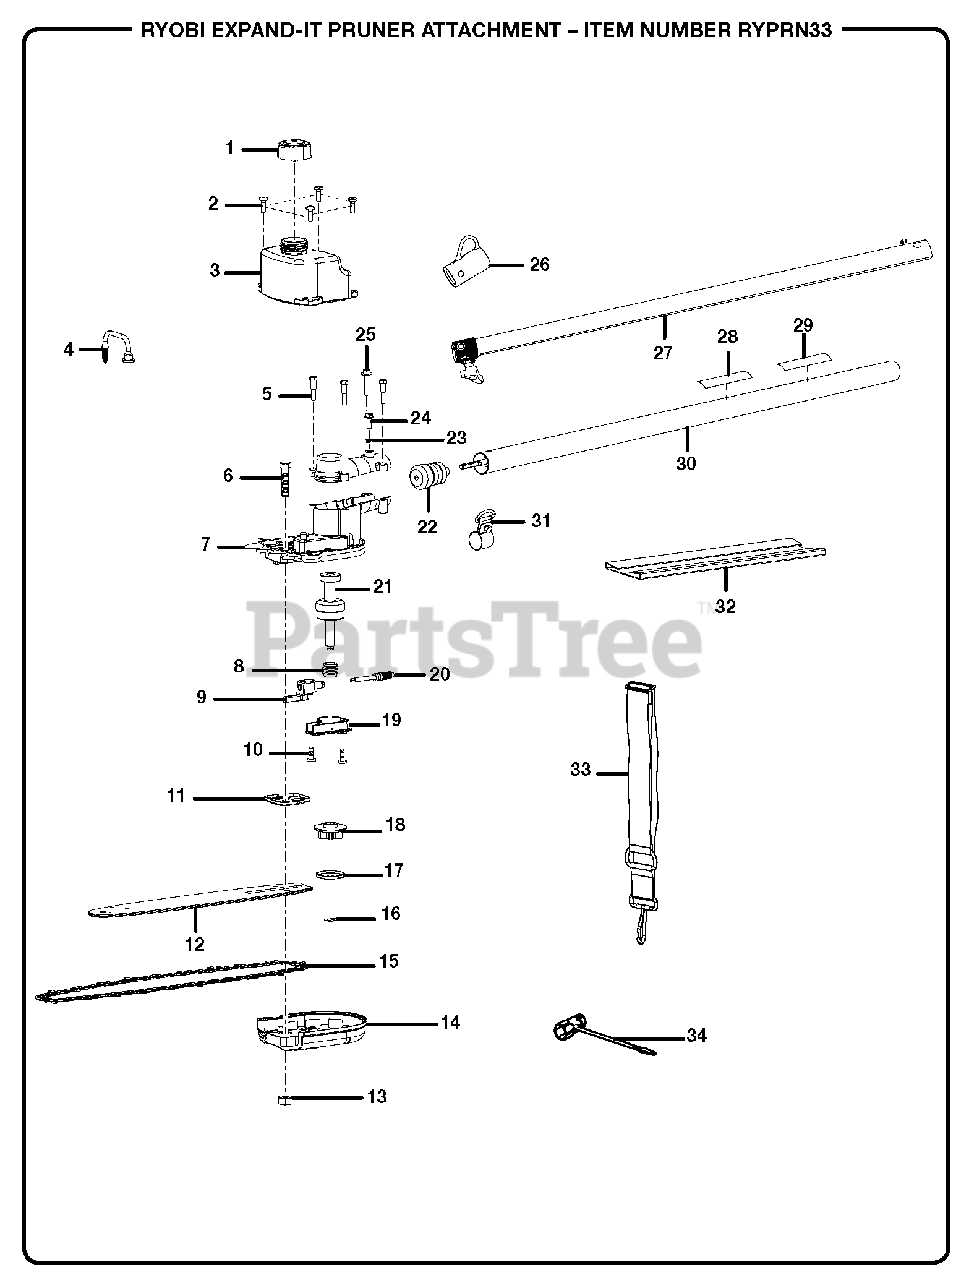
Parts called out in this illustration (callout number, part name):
1	Oil Cap Assembly
2	Screw (M5 x 18 mm)
3	Oil Tank Cover Assembly
4	Oil Pickup Tube
5	Screw (M5 x 25 mm)
6	Screw (M8 x 35 mm)
7	Gear Case Assembly
8	Worm Gear
9	Oil Pump Seal Assembly
10	Screw (M5 x 13 mm)
11	Bar Pad Plate
12	Guide Bar
13	Hex Nut (M8 x 1.25, Special)
14	Bar Clamp Assembly
15	Chain (10 in.)
16	E-Ring (Dia. 6 mm)
17	Cupped Washer
18	Sprocket
19	Oil Pump Housing w/Cam Pin Assembly
20	Pinion Gear and Plunger Assembly
21	Output Shaft Assembly
22	Pinion and Bearing Assembly
23	Lock Washer (5 mm)
24	Screw (M5 x 15 mm)
25	Screw (M5 x 25 mm)
26	Hanger Cap
27	Intermediate Boom Assembly
28	Logo Label
29	Warning Label
30	Lower Drive Shaft Assembly
31	Strap Hanger
33	Shoulder Strap
34	Combination Wrench
